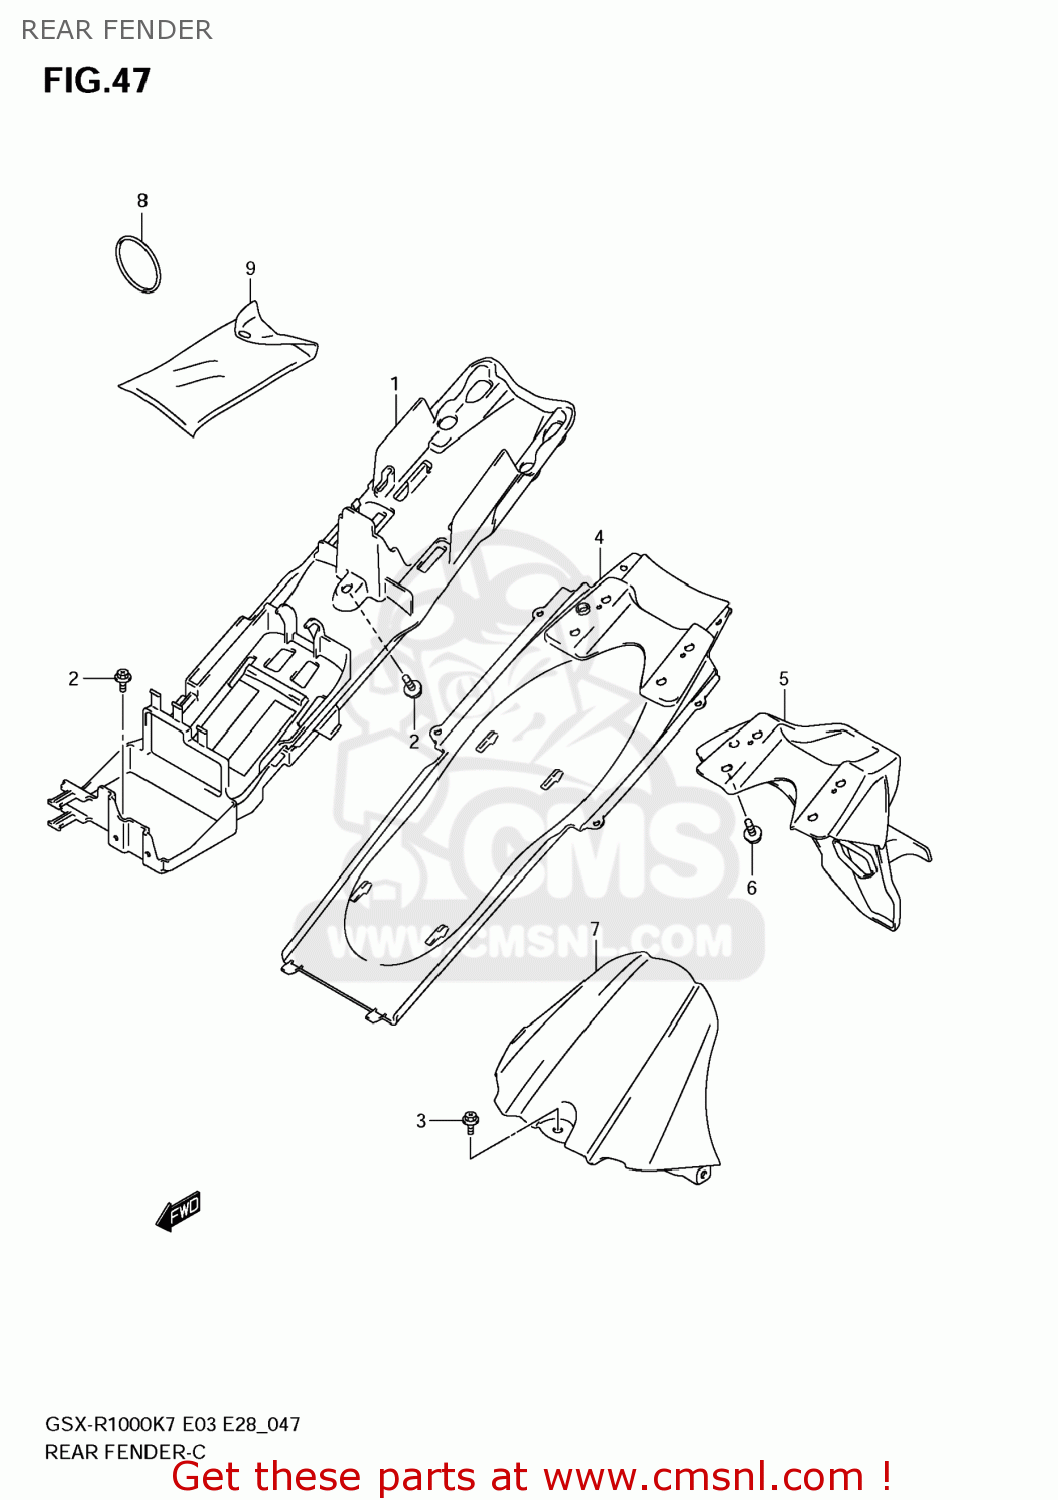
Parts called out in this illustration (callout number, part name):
1	FENDER,RR FR
2	BOLT
3	BOLT
4	COVER,RR FENDER FR
5	FENDER,RR RR
6	BOLT(6X16)
7	FENDER,RR LWR
8	O RING(D:3.5,ID:61)
9	TOOL ASSY
